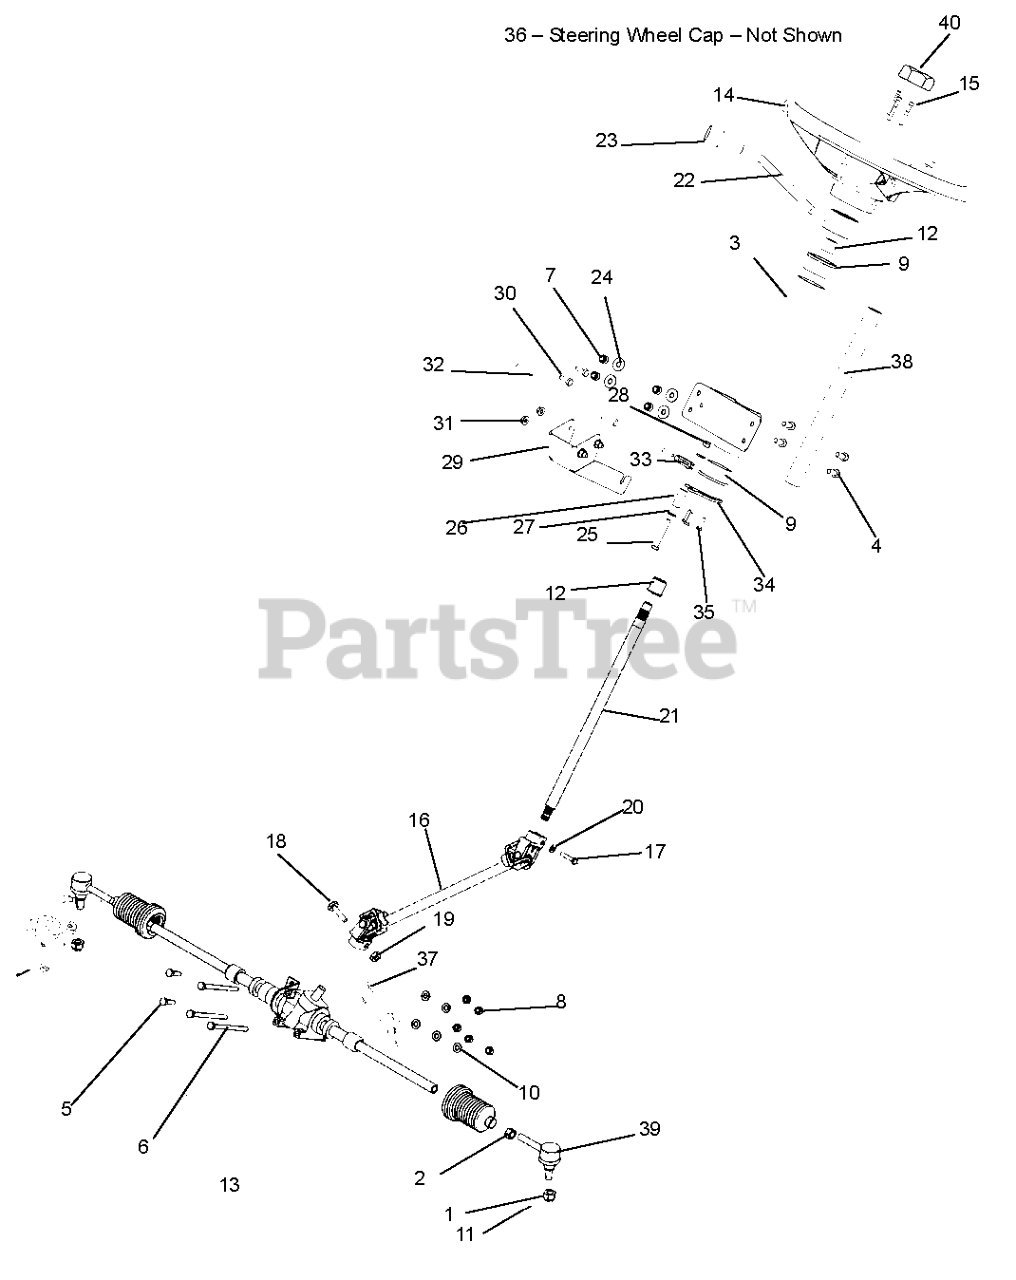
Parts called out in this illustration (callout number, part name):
1	NUT, HEX SLOTTED M12 X 1.25 YWZC
2	NUT, HEX M14 X 1.5 GR8.8 YWZC
3	STEERING COLUMN WELDMENT
4	BOLT, HEX .31-18 X .75 GR5 YWZC
5	BOLT, HEX .31-18 X 1.50 GR5
6	.31-18 X 4.50 GR5 YWZC
7	NUT, LOCK NYLOC .312-18 YWZC
8	NUT, LOCKING TOP FLANGE .31-18 YWZC
9	BUSHING, STEERING COLUMN, LARGE
10	WASHER, FLAT STEEL .38 X .875 X .083 YWZC
11	PIN, COTTER 3/32 X 1 LONG
12	BUSHING, STEERING COLUMN, SMALL
13	RACK & PINION ST
14	STEERING WHEEL, 3 SPK CONTOUR
15	BOLT, 10-24 X 1.25 SOCKET GR5 YWZC
16	STEERING SHAFT TRUCK
17	MVL BOLT FOR T840-093C
18	HHCS M10 X 1.5 X 35 PLT
19	NUT LOCK NYLOC M10 X 1.5 PLT
20	MVL SPRING WASHER FOR T840-093C
21	UPPER STEERING SHAFT TRUCK ASSEMBLY
22	WLDT, COLUMN SHIFT LEVER
23	SHIFTER KNOB
24	WASHER, FLAT STEEL .38 X .875 X .083 YWZC
25	BOLT, HEX .25-20 X 2.00 GR5
26	SHIFT STOP
27	WASHER, FLAT STEEL 281 X .62 X .065
28	NUT, LOCK NYLOC .250-20
29	CABLE BRACKET, SHIFTER
30	BOLT, HEX .25-20 X .75 GR5 YWZC
31	NUT, LOCKING FLANGE .25-20 YWZC
32	SHIFT CABLE (DASH)
33	YOKE 10-32 WITH LOCK
34	CAM, COLUMN SHIFTER
35	SHCS #10-24 X .750
37	SPACER, STEERING
38	SHAFT, COLUMN SHIFTER
39	TIE ROD END
40	NUT HEX M16X2.00X8MM THK PLT
